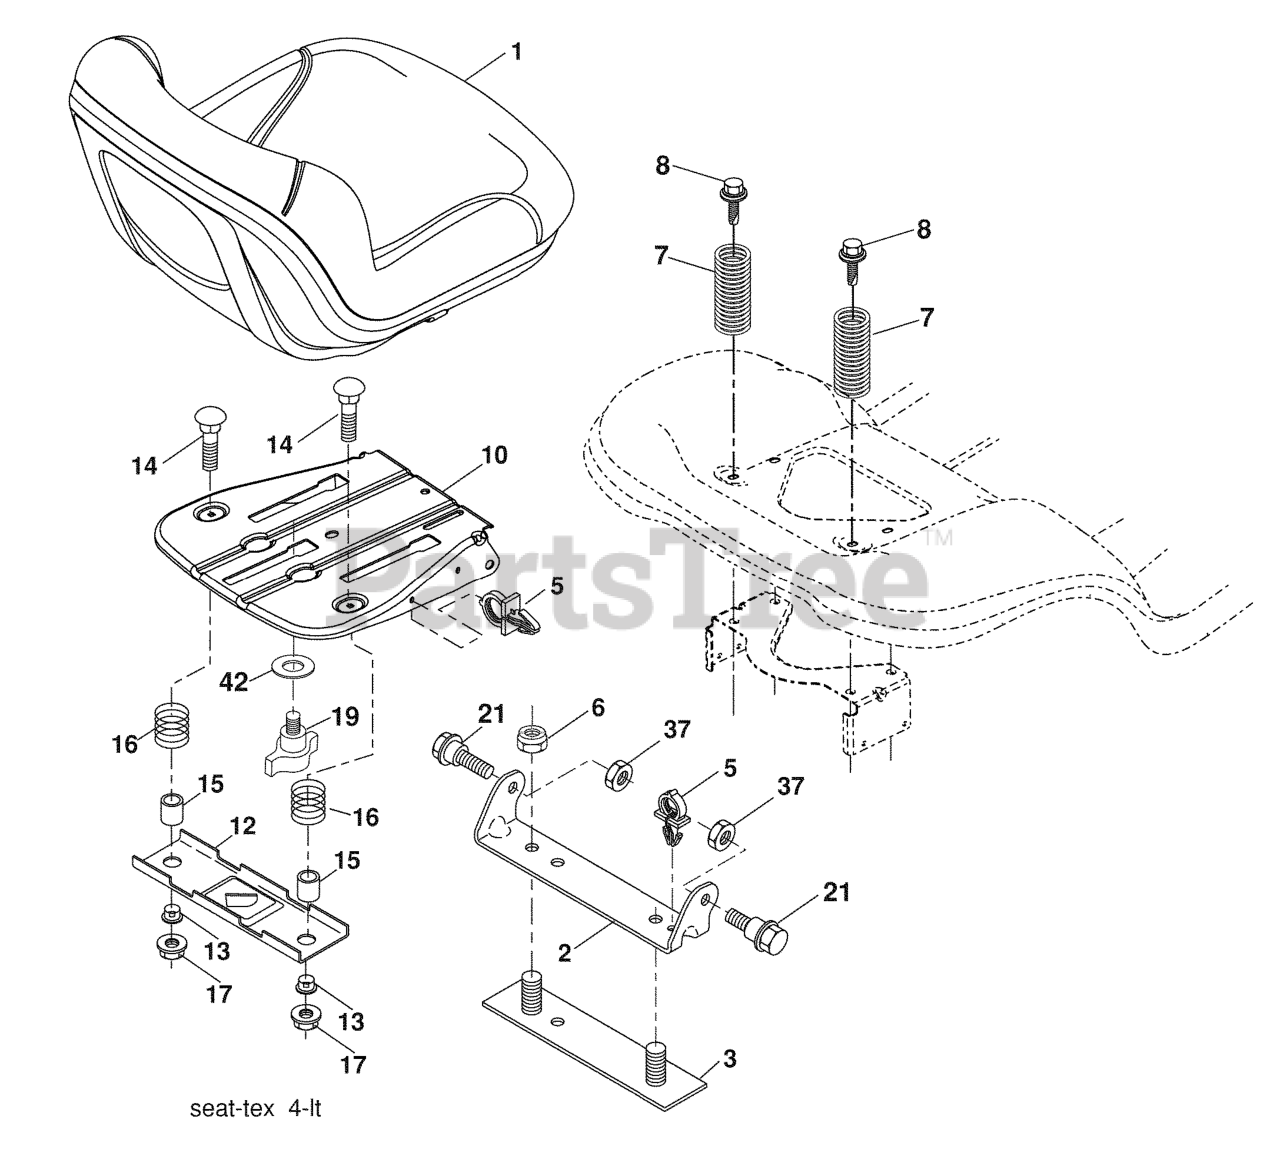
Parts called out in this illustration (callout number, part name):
1	SEAT.TH130.GRY.MILSCO.
2	BRKT.PIVOT.FENDER
3	STRAP
6	NUT
7	SPRING COMPRESSION
8	BOLT.5/16-18UNCX3/4 W/SEMS.BLK
10	PAN.ASM.SEAT.SHORT
12	BRKT.MNT.OPC.SW.SEAT.
14	BOLT.ROUND.HEAD.SQUARE.NECK
15	SPACER SPLIT 28X.96
16	SPRING COMPRESSED
17	NUT T
19	KNOB.SEAT.ADJ.
21	BOLT.SHOULDER.5/16-18
37	NUT.71038.31-18.HEX.NYLOCK
42	WASHER.CUP.SEAT.
